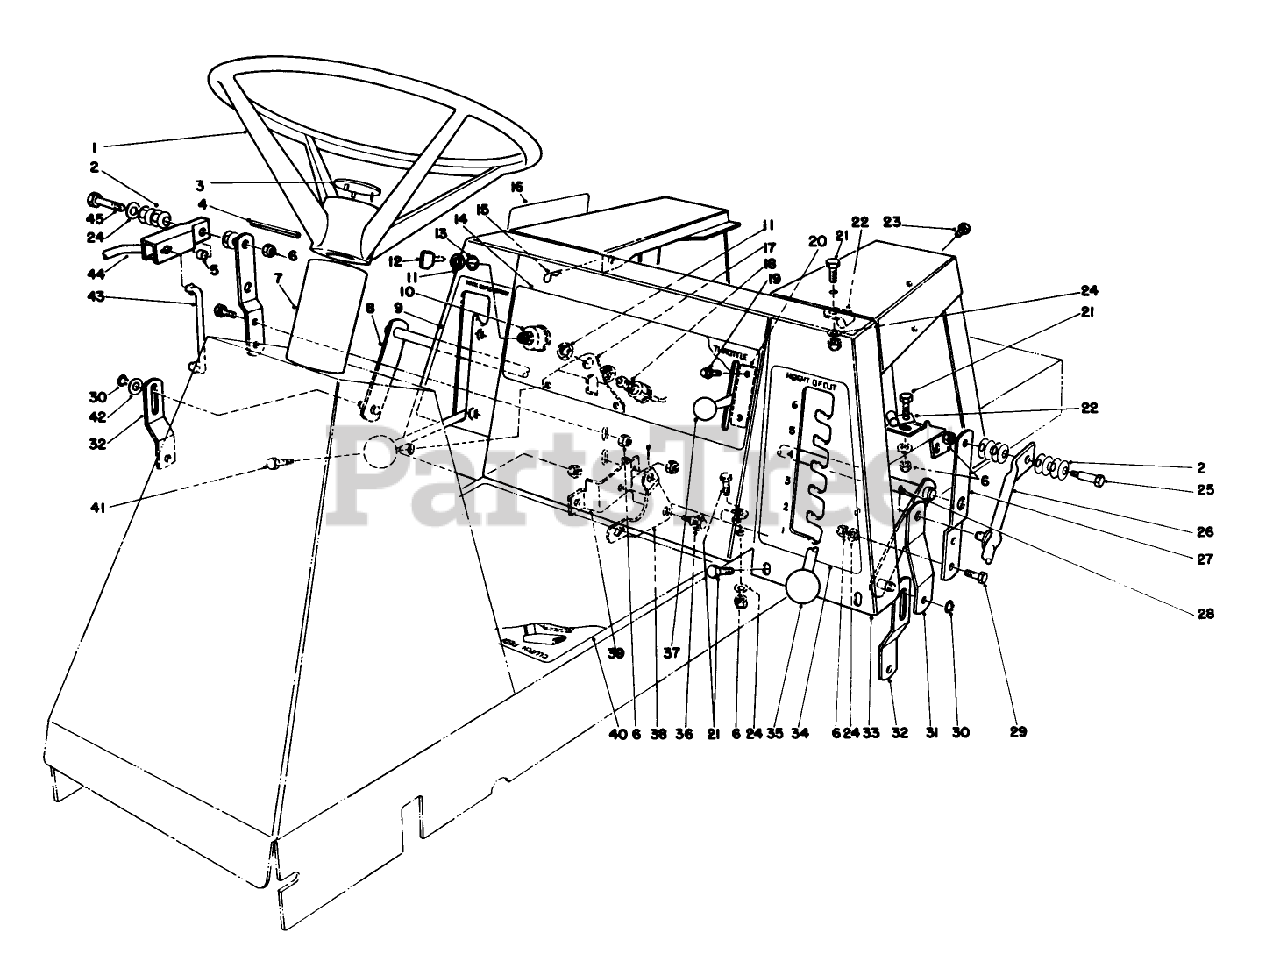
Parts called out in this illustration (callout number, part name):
1	STEERING WHEEL ASM
2	WASHER-BELLEVILLE
4	PIN-ROLL
5	SPACER
6	NUT-LOCK, NI
7	STRG. SHAFT COVER
12	KEY-IGNITION
13	WASHER-LOCK
17	SWITCH MT BRKT
18	DECK SWITCH
19	SCREW-HWHTF
20	THROTTLE CONTROL
21	SCREW-HH
22	CLAMP
23	SCREW-HH
24	WASHER-PLAIN
25	BOLT-SHOULDER
26	HOC LEVER WA *B
28	PIN-COTTER
29	SCREW-HH
30	RING-RETAINING
34	HOC DECAL
36	SCREW-SHOULDER
38	DECK ENGAGE BELLCRANK
41	SCREW-HH
42	WASHER-FLAT
43	BELLCRANK LINK(PLTD)
44	SHIFT LEVER WA *B
45	SCREW-HH
